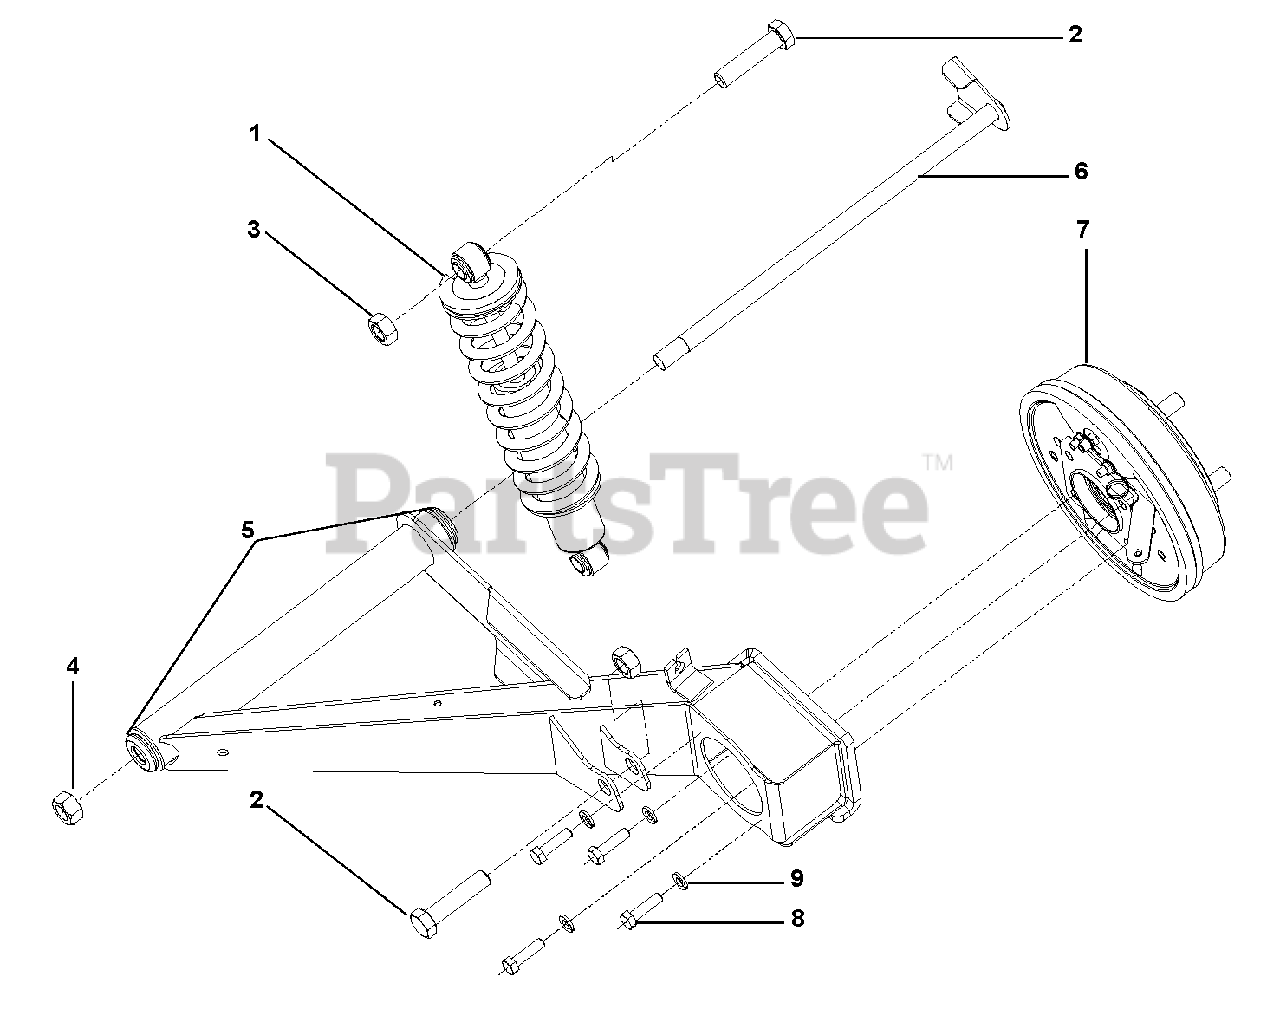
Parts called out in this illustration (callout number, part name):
1	SHOCK, COIL REAR TRUCK
2	HHCS M14 X 2.00 X 60 GR8.8
3	NUT, HEX NYLOCK M14 X 2.00
4	NUT, LOCK TOP .563-12 GR5 YWZC
5	BUSHING IDLER ARM RUBBER
6	CENTER PIVOT TUBE WELDMENT
7	RIGHT HAND DRUM ASM 18 OMM 4 ON 4" BC
8	HHCS M8 X 1.25 X 30 GR 10.9 YLW PLT
9	WASHER, LOCK M8 YWZC
